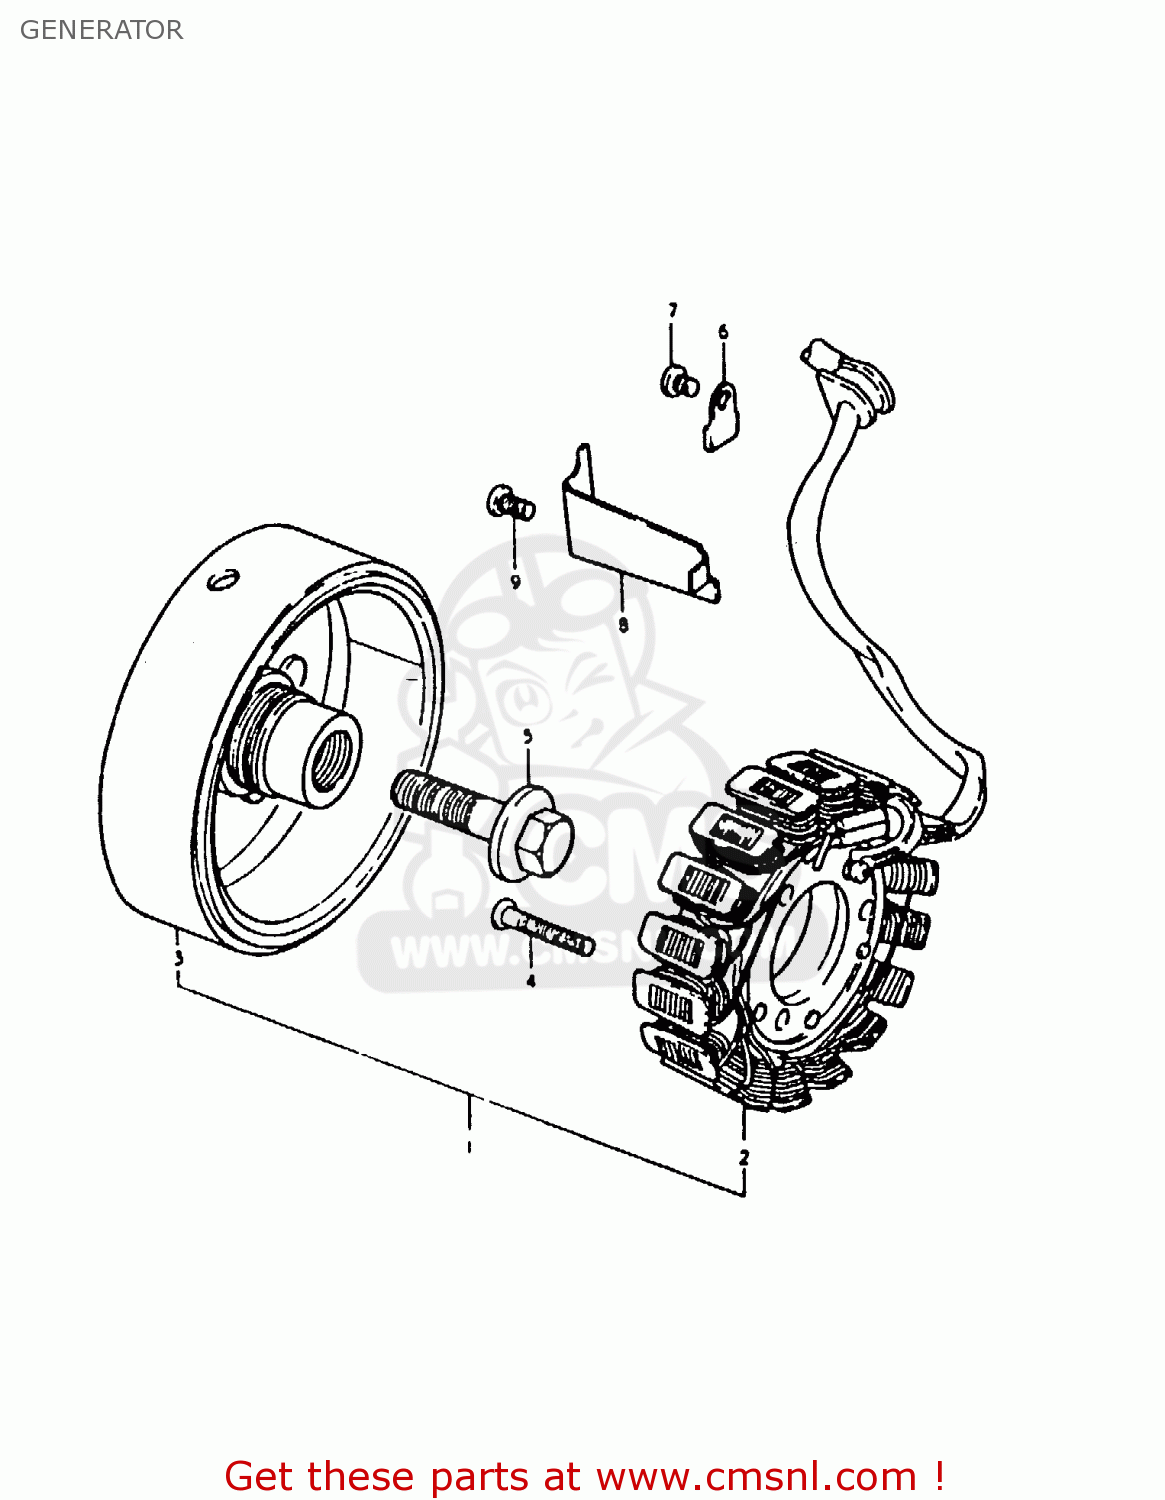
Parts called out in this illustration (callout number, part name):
1	GENERATOR ASSEMBLY
2	STARTER ASSY
3	ROTOR ASSEMBLY
4	SCREW
5	BOLT
6	CLAMP,GENERATOR LEAD WIRE
7	SCREW
8	CLAMP,GENERATOR LEAD WIRE
9	SCREW
